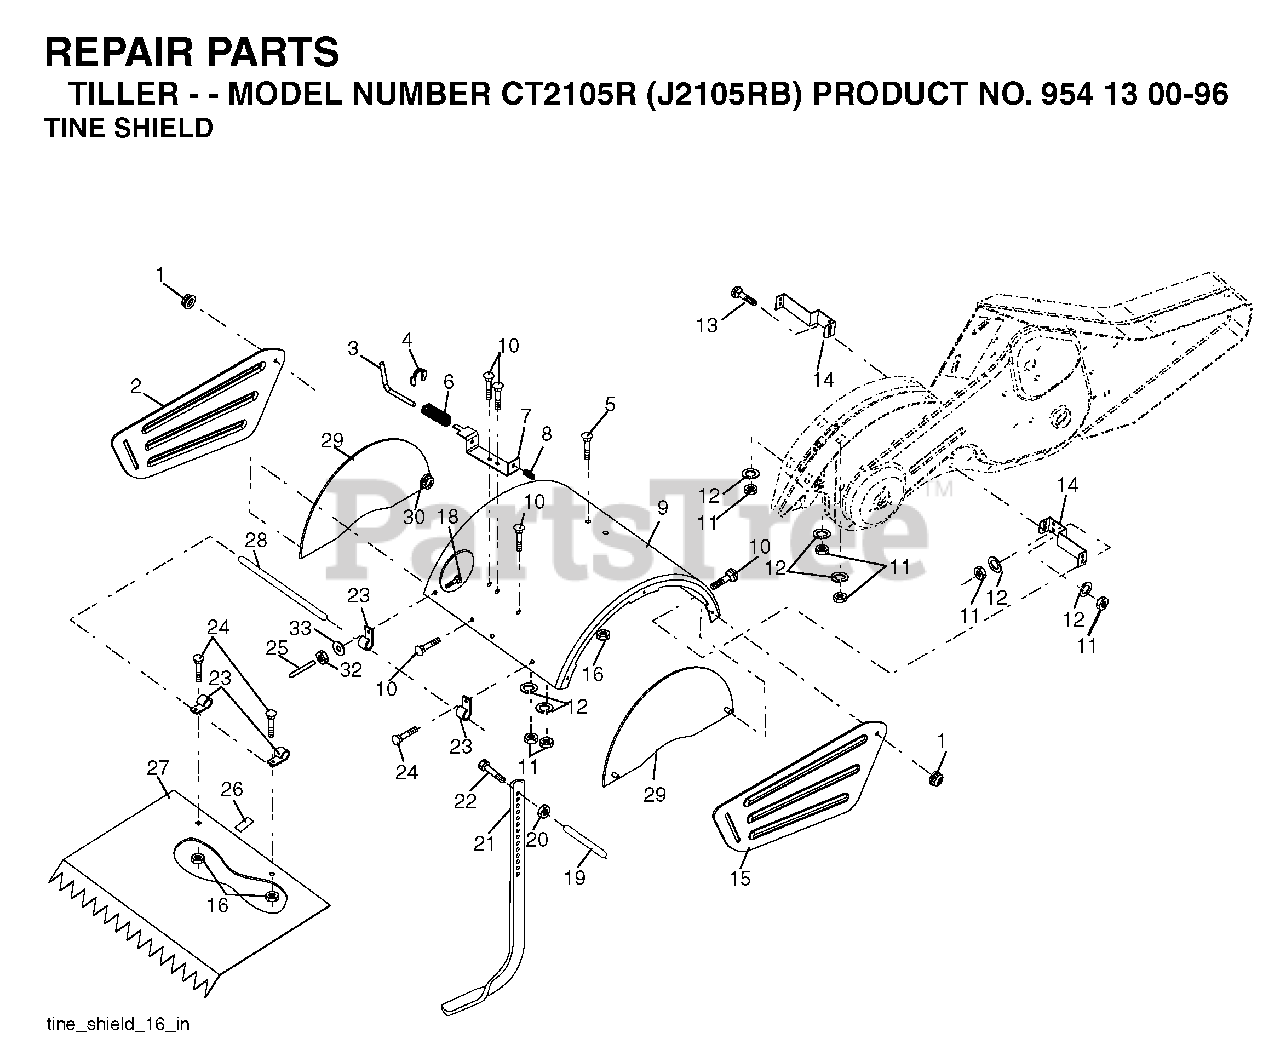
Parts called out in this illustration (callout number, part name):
1	NUT LOCK HEX FLANGE 5/16-18
3	STAKE PIN TI
4	RING, KLIP
5	BOLT, RDHD SQNK 5/16-18 X 3/4
6	SPRING TI
7	LATCH BRACKET TI
8	SPRING CRT
10	BOLT
12	LOCKWASHER
13	BOLT.CARRIAGE.5/16-18
14	BRACKET.TINE.SHIELD.TILLER
16	NUT T
20	NUT.HEX.3/8-16UNC
21	STAKE DEPTH CRT
22	BOLT.375-16
23	HINGE CRT
25	VINYL CAP TI
26	PAD IDLER TI
28	PIN.HINGE.TILLER
30	LOCKNUT-FLANGE 5/16-18
32	NUT
33	LOCKWASHER
